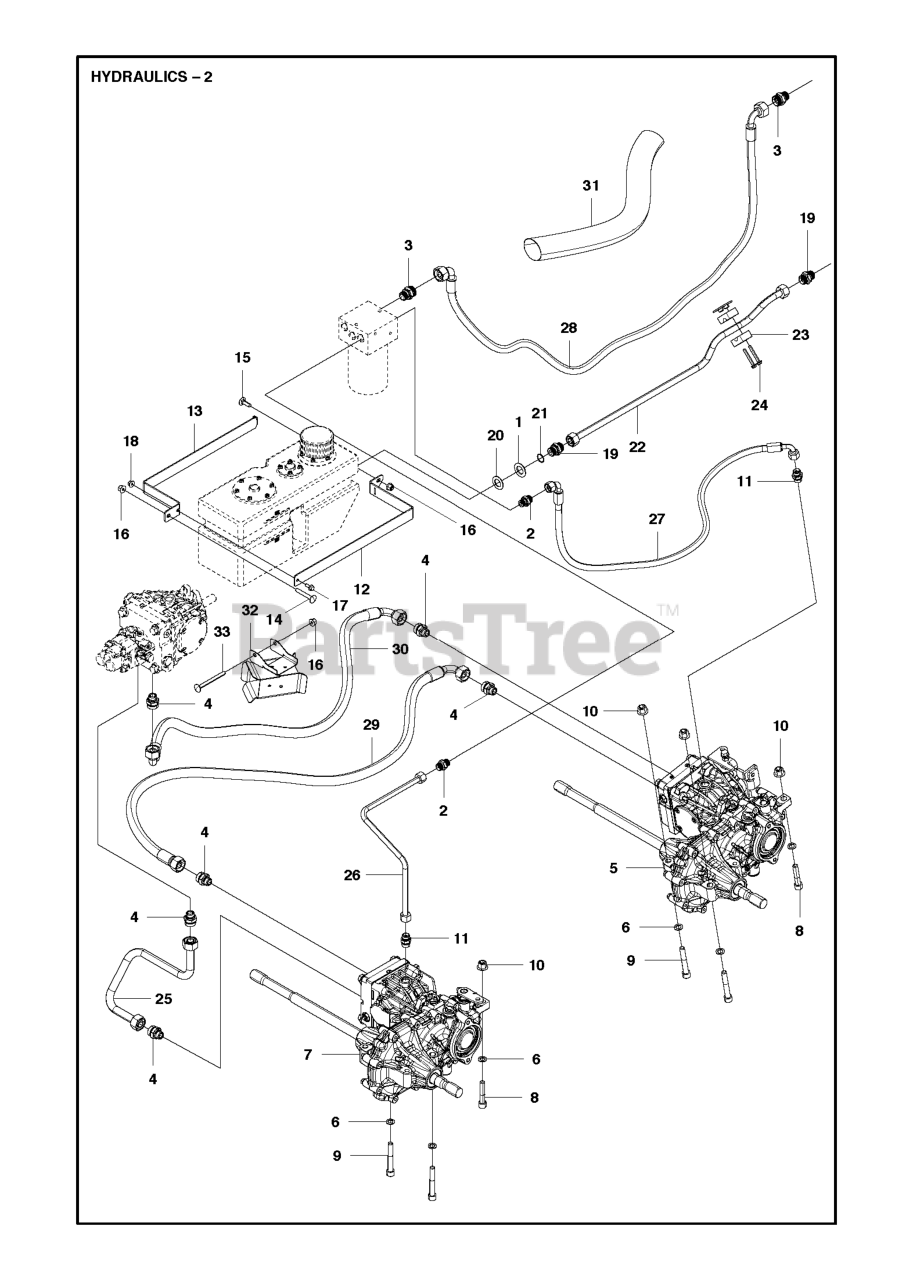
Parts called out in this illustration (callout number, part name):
16	NUT FLANGE
17	Screw
18	NUT FLANGE
